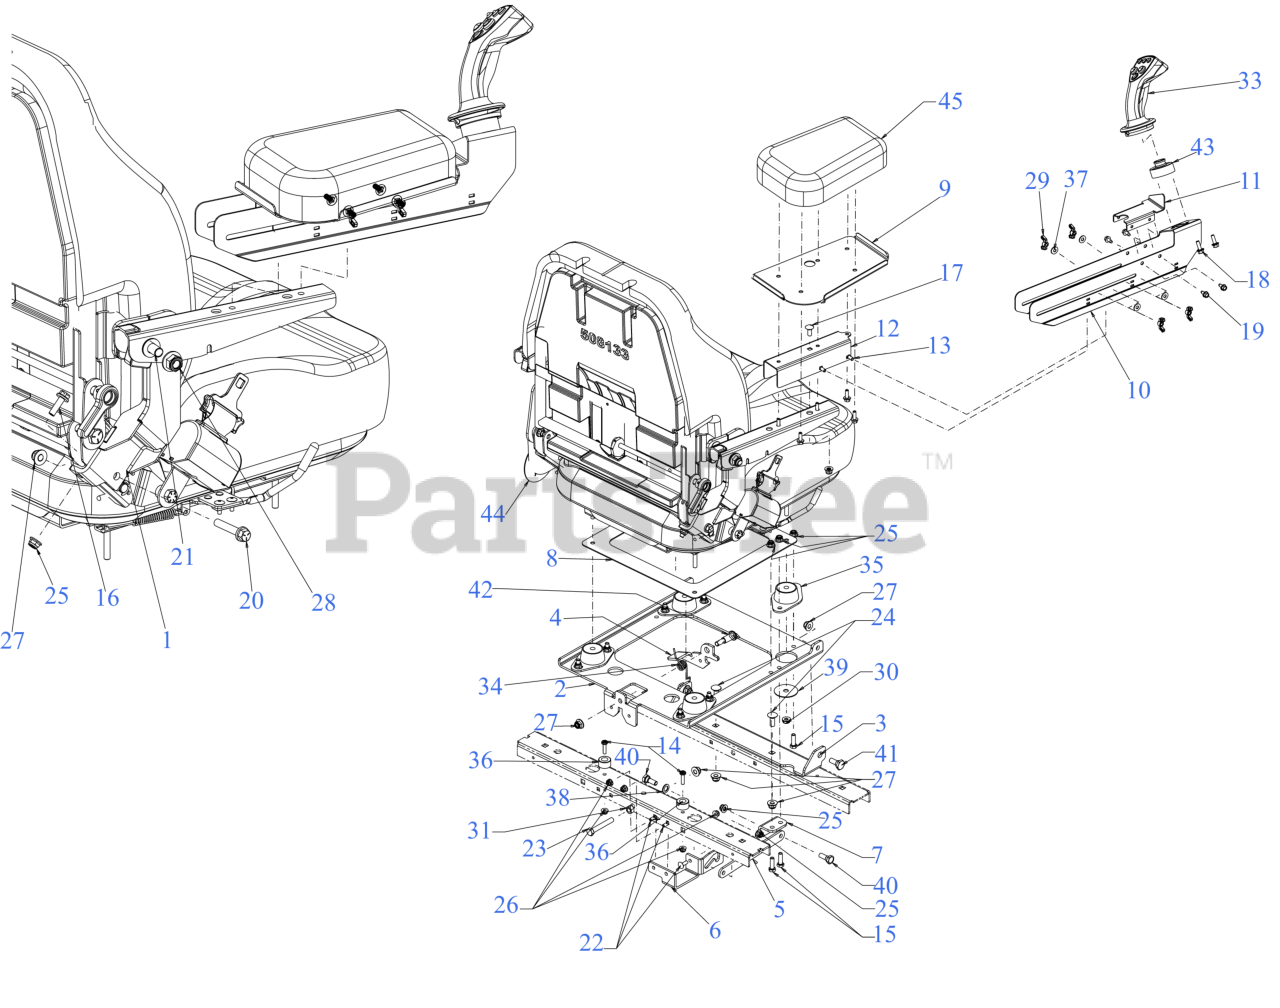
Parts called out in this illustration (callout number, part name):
1	ARMREST MOUNT (RH)
2	SEAT MOUNTING BRACKET
4	SEAT LATCH LEVER
5	SEAT LOCKOUT BRACKET
6	SEAT LOCKOUT MOUNT
9	PAD MOUNT PLATE
10	ARMREST BRACKET (RH)
11	JOYSTICK COVER BRACKET
12	ARMREST BRACKET
13	CARRIAGE BOLT 1/4-20 x .62
14	MACHINE SCREW 1/4-20:1
15	SCREW 5/16-18 x 1.0 GR5
16	SCREW 5/16-18 x 1 GR5
17	CARRIAGE BOLT 5/16-18 x .75
18	SCREW 1/4-20 x .75 GR5
19	SCREW 1/4-20 X.500
20	SCREW 3/8-16 x 2.00 GR5
21	HHCS:1/2-13:3.50:GR5:SPEC
22	SCREW 1/4-20 x .75 GR5
23	HEX SCREW-3/8-16X2.5 GR5
24	CARRIAGE BOLT 3/8-16 x 1.00 GR5
25	FLANGE LOCK NUT 5/16-18
26	FLANGE LOCK NUT
29	WING NUT 1/4-20
30	HEX FLANGE NUT
32	HEX NUT TOP LOCK 5/16-18 GR 8
34	TORSION SPRING
35	SEAT MOUNT
37	FLAT WASHER .271:.630:.065
38	FLAT WASHER .469X.750X.054
39	HUB CAP WASHER .406 x 1.92 x .060
40	SHOULDER SCREW .437
41	SHOULDER SCREW
42	SHOULDER SCREW .50X.925
43	JOYSTICK MOUNT
44	SEAT (ELEC LUMBAR)
44	ISO LEVER W/ROLL P
44	AIR COMPRESSOR HARNESS
44	TRACK KIT-7" HD SINGLE LOCK
44	BELLOWS-W/HARDWARE
44	AIR COMPRESSOR KIT
44	SET OF ARM PADS
44	SET OF FRONT ADJUST ARMS PADDED
44	SEAT KNOB KIT
44	2" RETRACTABLE BELT KIT
44	HOSE KIT WITH AIR VALVE
44	RATCHET CLIP .250
44	BACK COVER WITH LOGO
44	AIR VALVE PADDLE TYPE
44	SEAT SWITCH NC/NO
45	ARMREST PAD
